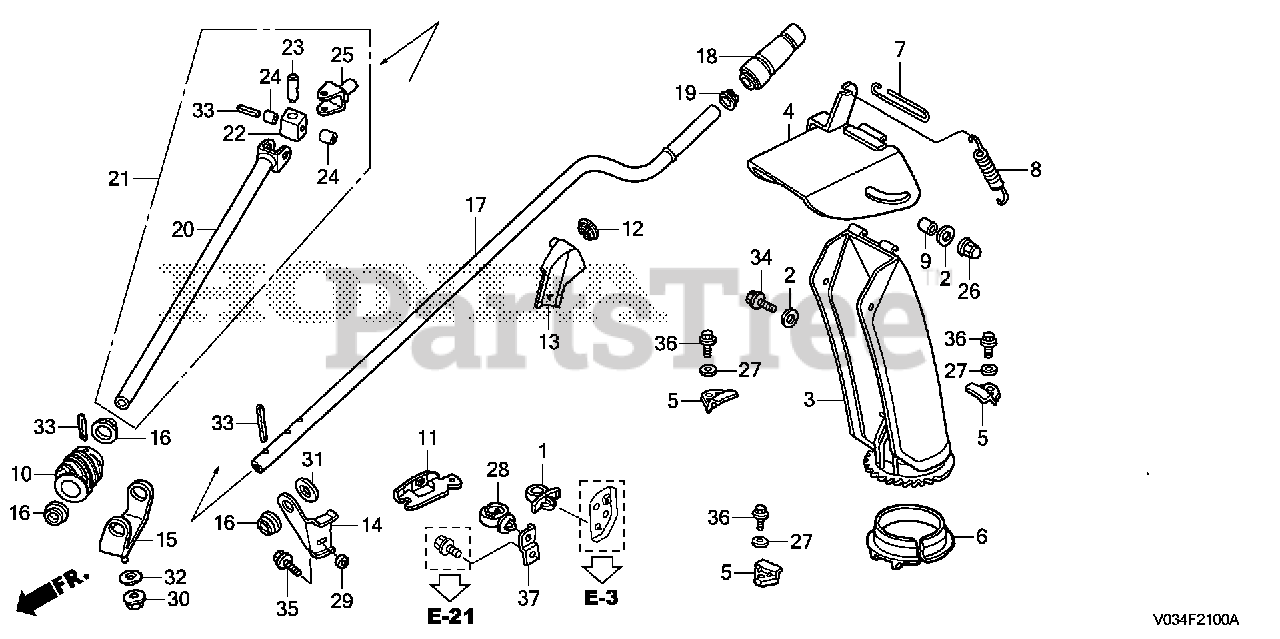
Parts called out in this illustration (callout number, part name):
2	WASHER, ACCELERATOR PEDAL
4	GUIDE, CHUTE (COO)
5	PLATE, CHUTE SETTING
6	BUSH, CHUTE
7	PIN, CHUTE GUIDE
8	SPRING, CHUTE
9	COLLAR, CHUTE GUIDE
10	GEAR, CHUTE DRIVE
11	HOLDER, HANDLE BRACKET
12	BUSH, CHUTE HANDLE
13	BRACKET A, CHUTE HANDLE
14	BRACKET B, CHUTE HANDLE
15	STAY, DRIVE GEAR
16	BUSH, DRIVE GEAR
17	HANDLE, CHUTE (UPPER)
18	GRIP, CHUTE HANDLE
19	BUSH A, CHUTE HANDLE
20	HANDLE, CHUTE (LOWER)
21	HANDLE, CHUTE (LOWER)
22	PIECE, JOINT
23	PIN A, JOINT
24	PIN B, JOINT
26	NUT, CAP (6MM)
27	WASHER, CHUTE SETTING
28	CLIP, WIRE HARNESS (25MM)
29	COLLAR (6.6X13.8X6)
30	NUT, FLANGE (8MM)
31	WASHER, PLAIN (16MM)
32	WASHER, PLAIN (8MM)
33	PIN, SPRING (4X28)
34	BOLT, FLANGE (6X14)
35	BOLT, FLANGE (6X18)
36	BOLT, FLANGE (8X12)
37	BASE, CLIP
